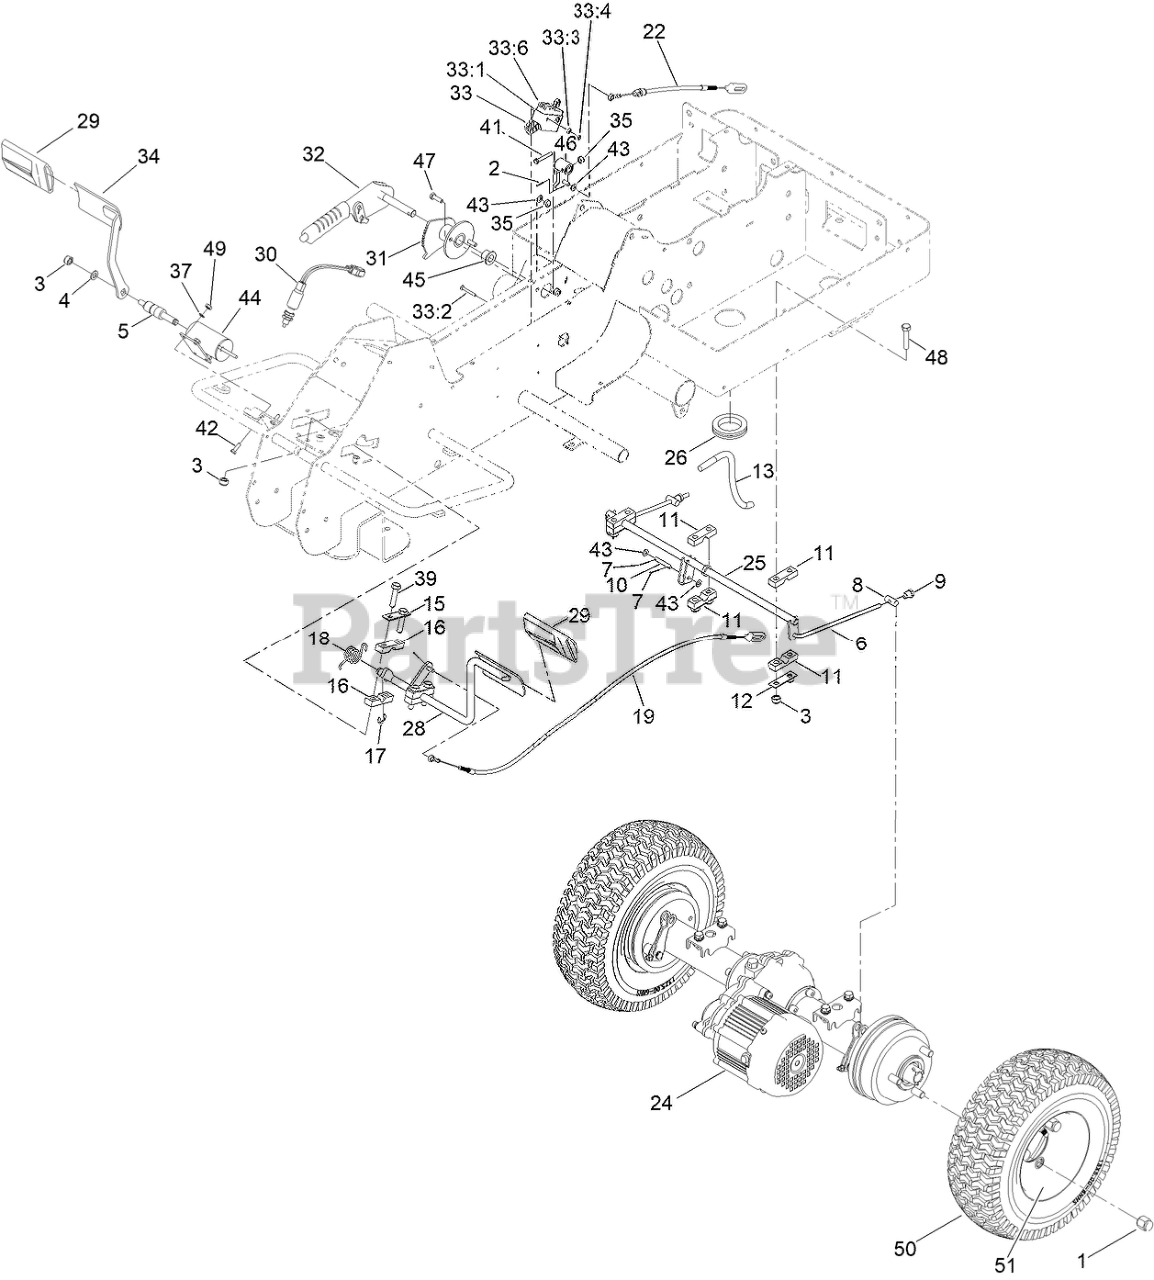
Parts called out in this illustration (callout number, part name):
2	BOBBY PIN
3	NUT-HEX, NI
4	WASHER
5	SHAFT, THROTTLE
6	ROD, BRAKE CONNECTION
7	BOBBY PIN
8	PIN, BRAKE CONNECTION (FLAT)
9	NUT , BRAKE ADJUSTMENT
10	PIN, BRAKE CABLE
11	MOUNTING, BRAKE ROD
12	PLATE, BRAKE MOUTING
13	COVER, WIRE
15	PLATE, PEDAL MOUTING
16	BLOCK, PEDAL HOLDER
17	CLIP, PEDAL HOLDER
18	SPRING, PEDAL
19	CABLE, PEDAL BRAKE
22	CABLE, HAND BRAKE
24	TRANSMISSION ASSEMBLY
25	REAR TRANSISION ASM
26	INSERT, WIRE (SMALL)
28	BRAKE PEDAL ASM
29	COVER, PEDAL
30	BRAKING SWITCH ASM
31	HAND BRAKE, HUB ASM
32	HAND BRAKE, HANDLE ASM
33	SWITCH ASM
33:1	COVER, SWITCH
33:3	WASHER
33:6	HOUSING, BRAKING SWITCH
34	PEDAL, LEFT
35	NUT-NYLOC
37	WASHER
39	BOLT
42	SCREW-HH
43	WASHER-PLAIN
44	HUB ASM, THROTTLE
45	BUSHING, PARKING BRAKE
46	ASM, SWITCH PIVOT
47	SCREW-HH
48	BOLT
50	TYRE, WHEEL
51	HUB, REAR WHEEL
